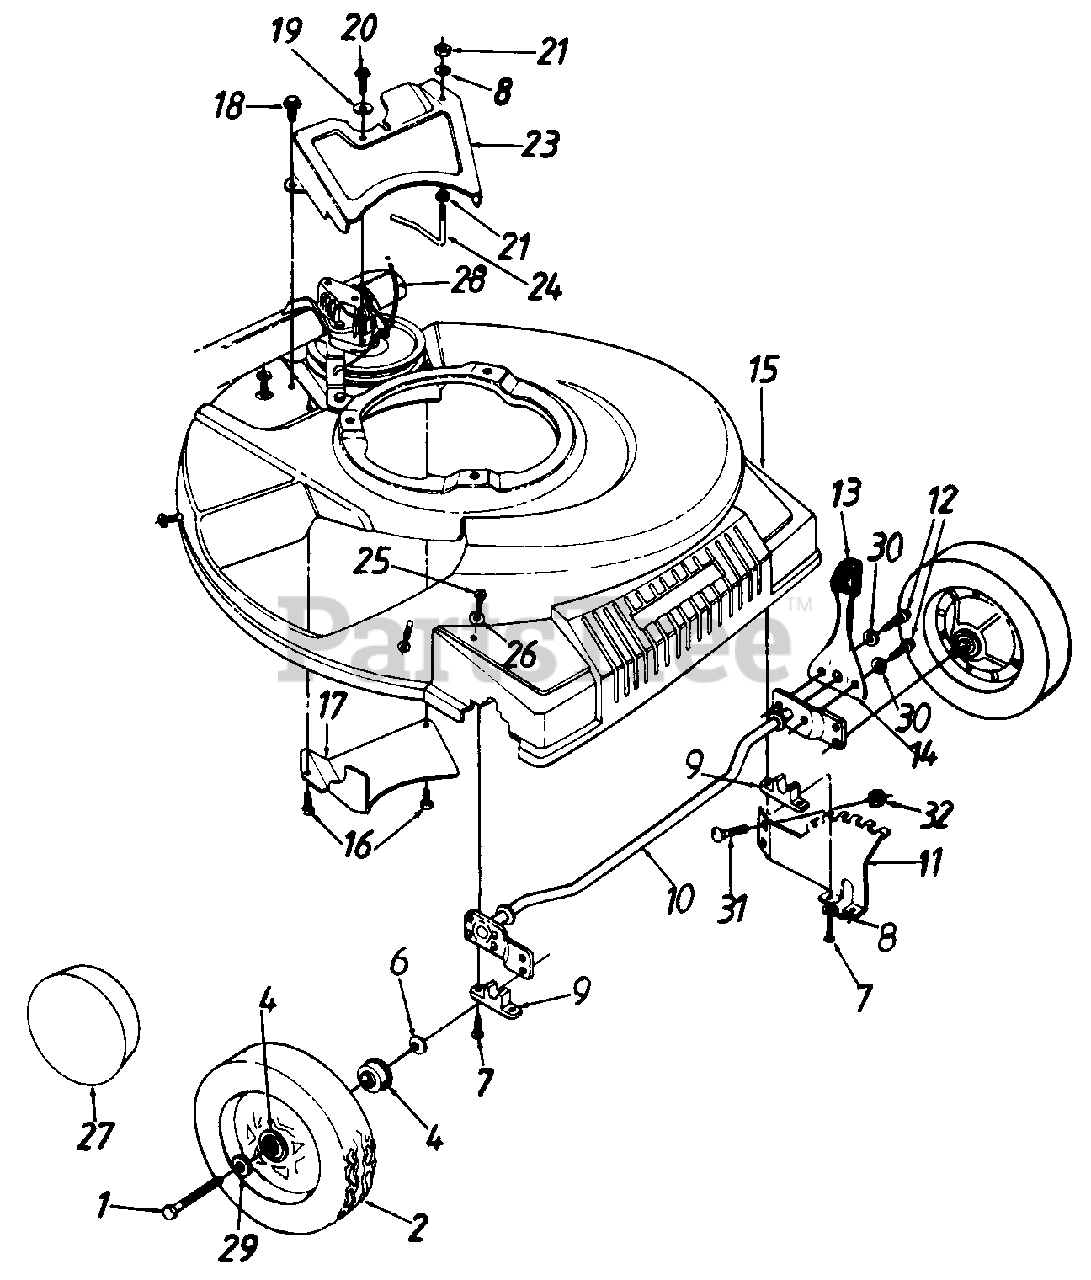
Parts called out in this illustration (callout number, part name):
1	Front Axle Bolt
2	Wheel Ass'y. Comp. (Beige)
4	Flange Ball Brg. .501" I.D.
6	Bell-Wash. .380" I.D. x .88
7	Hex Wash. Hd. Scr. 1/4-20 x 1" Lg.
8	L-Wash. 1/4" I.D.
9	Block Bushing
10	Axle Ass'y.
11	Height Adj. Bracket
12	Hex Wash. Hd. TT-Tap Scr. 1/4-20 x .38" Lg.
13	Knob
14	Spring Lever
15	Plastic Front End (Black)
16	Hex B-Tap Scr. 1/4" x .38"
19	Bell-Wash. .265" I.D. x .75"
20	Hex Wash. Hd. B-Tap Scr. 1/4 x .62" (Spec.)
21	Hex Nut 1/4-20 Thd.
25	Torx Truss Hd. Scr. 5/16 x .75"
26	Bell-Wash. .345" I.D. x .88" O.D.
27	Hub Cap (Beige)
28	S.P. Cable 50" Lg.
29	Wave Wash. .51" I.D. x .75"
30	External L-Wash. 1/4" I.D.
31	Carr. Bolt 1/4-20 x .5" Lg.
32	Hex L-Nut 1/4-20 Thd.
